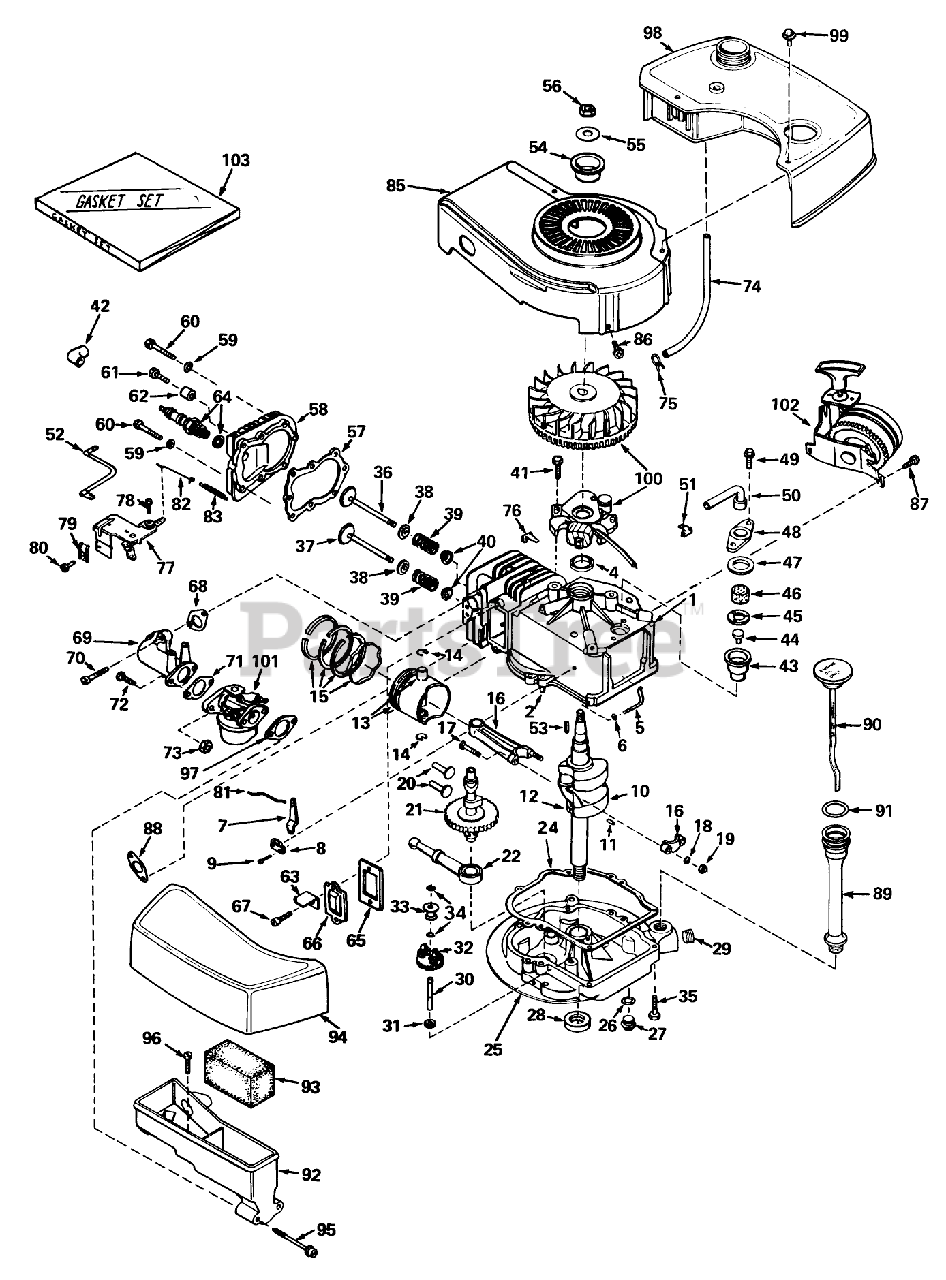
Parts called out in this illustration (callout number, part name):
1	Cylinder Assy. (Incl. Ref. #2, 4 105)
2	Pin-Dowel
4	OIL SEAL
5	Rod, Governor (Incl. No. 36)
6	Washer-Flat
7	Governor Lever
8	Clamp-Lever, Governor
9	Screw
10	Crankshaft Assembly (Incl. Nos. 12 13)
11	Pin, Groove
12	Gear, Crankshaft
13	Piston Pin Assembly (Incl. 2 of No. 14) (.010 Oversize)
13	Piston Pin Assembly (Incl. 2 of No. 14) (.020 Oversize)
14	Ring-Retaining, Piston Pin
15	Ring Set Piston (Std.)
15	Ring Set Piston (.010 Oversize)
15	Ring Set Piston (.020 Oversize)
16	Rod Assy., Connecting (Incl. Ref. #17)
17	Bolt, Connecting
18	Washer
19	LOCKNUT
20	Lifter-Valve
21	Camshaft
22	Oil Pump ASM
24	Gasket, Mounting
25	Filter, Air Cleaner
26	Gasket-Oil Drain
27	Plug Oil Drain
28	Seal Oil
29	Plug Oil Drain
30	Shaft-Governor
31	Washer-Flat
32	Governor Gear ASM
33	Spool-Governor
34	Ring-Retaining
35	Screw (1/4-20 x 1-1/4)
36	Valve, Intake (Incl. Ref. #38, 39 40) (Std.)
36	Valve, Exhaust (1/32" Oversize) (Incl. Nos. 8, 9 10)
37	Valve, Exhaust (Standard) (Incl. Nos. 8, 9 10)
37	Valve, Exhaust (1/32" Oversize) (Incl. Nos. 8, 9 10)
38	Cap-Upper Valve Spring
39	Spring-Valve
40	Cap-Valve, Spring
41	Screw
42	Cover-Spark Plug
43	Body Breather Tube
44	Valve Check
45	2000A37 WIZARD ROTA
46	Element-Breather
47	Gasket-Breather
48	Cover Breather
49	Screw, Hex Hd. w/Conical
50	Tube, Breaker
51	Clip, Breather
52	Wire, Ground
53	Key Flywheel
55	Washer
56	Hex Nut
57	63573 GIL 42 SNWTHW
58	Head Cylinder
59	Washer
60	Screw
61	Screw Hex Hd. Cap
62	Space
63	Retainer Clip
64	Plug, Spark (J17LM or equiv.)
65	Gasket-Breather
66	Cover-Valve
67	Screw
68	Gasket, Intake
69	Pipe, Intake
70	Screw (1/4-20 x 1)
71	Gasket
73	Nut and Lock Washer (1/4-28)
74	Line, Fuel
75	Clamp-Line, Fuel
76	Clip-Wire
77	Control Assy., Speed
78	Screw (10-24 x 3/4)
79	Conduit
80	Screw (10-32 x 3/8)
81	Link Governor
82	Link Governor Spring
83	Spring Governor
85	Housing, Blower
86	Screw
87	Screw (1/4-20 x 1/2)
88	Gasket Exhaust
89	Tube, Oil Filler
90	Dipstick, OiI (Incl. No. 91)
91	O-Ring
92	Body Air Cleaner
93	Filer, Air
94	Cove, Air Cleaner
95	Screw Fil Hd.
96	Screw, Hex Hd.
97	Gasket-Air Cleaner
98	Tank Fuel
99	Screw (10-32 x 35/64)
100	Magneto
101	Carburetor
102	Starter, Side Mount
103	53024/VAR.16HP O/P
